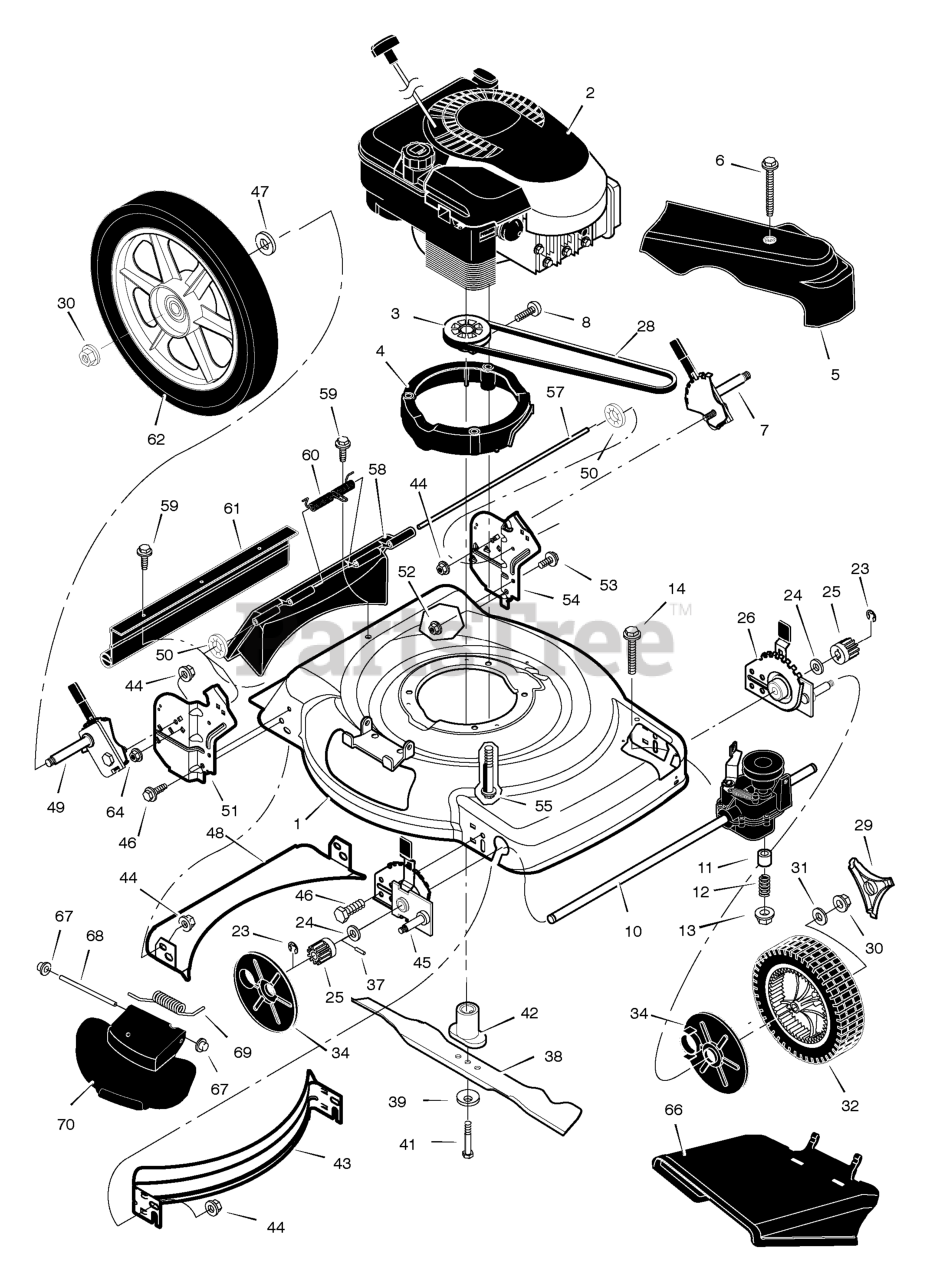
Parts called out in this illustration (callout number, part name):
2	Engine *
3	Pulley, Drive
4	Spacer, Engine
5	Cover, Belt (Black)
6	Screw
7	Adjuster, Left Rear Height
8	Screw
10	Transmission *
12	Spring, Compression
13	Nut
14	Bolt
25	Gear, Pinion
26	Adjuster, Left Front Height
29	Cap, Hub (Gray)
30	Nut, Flange
31	Washer
32	Wheel & Tire, Front (Gray)
34	Cover, Dust
37	Pin, Drive
38	Blade
39	Washer, Belleville
42	Adapter, Blade
43	Baffle, Front
44	Nut, Flange
45	Adjuster, Right Front Height
46	Bolt
48	Baffle, Rear
49	Adjuster, Right Rear Height
50	Retainer, Push
51	Bracket, Right Handle
52	Nut, Flange
53	Bolt
54	Bracket, Left Handle
55	Bolt, Engine
57	Rod, Pivot
58	Door, Rear (Black)
60	Spring
61	Guard, Rear
62	Wheel & Tire, Rear (Gray)
64	Nut
66	Deflector, Chute (Black)
67	Push On Cap
68	Rod, Pivot
69	Spring, Torsion
70	Cover, Mulch (Black)
